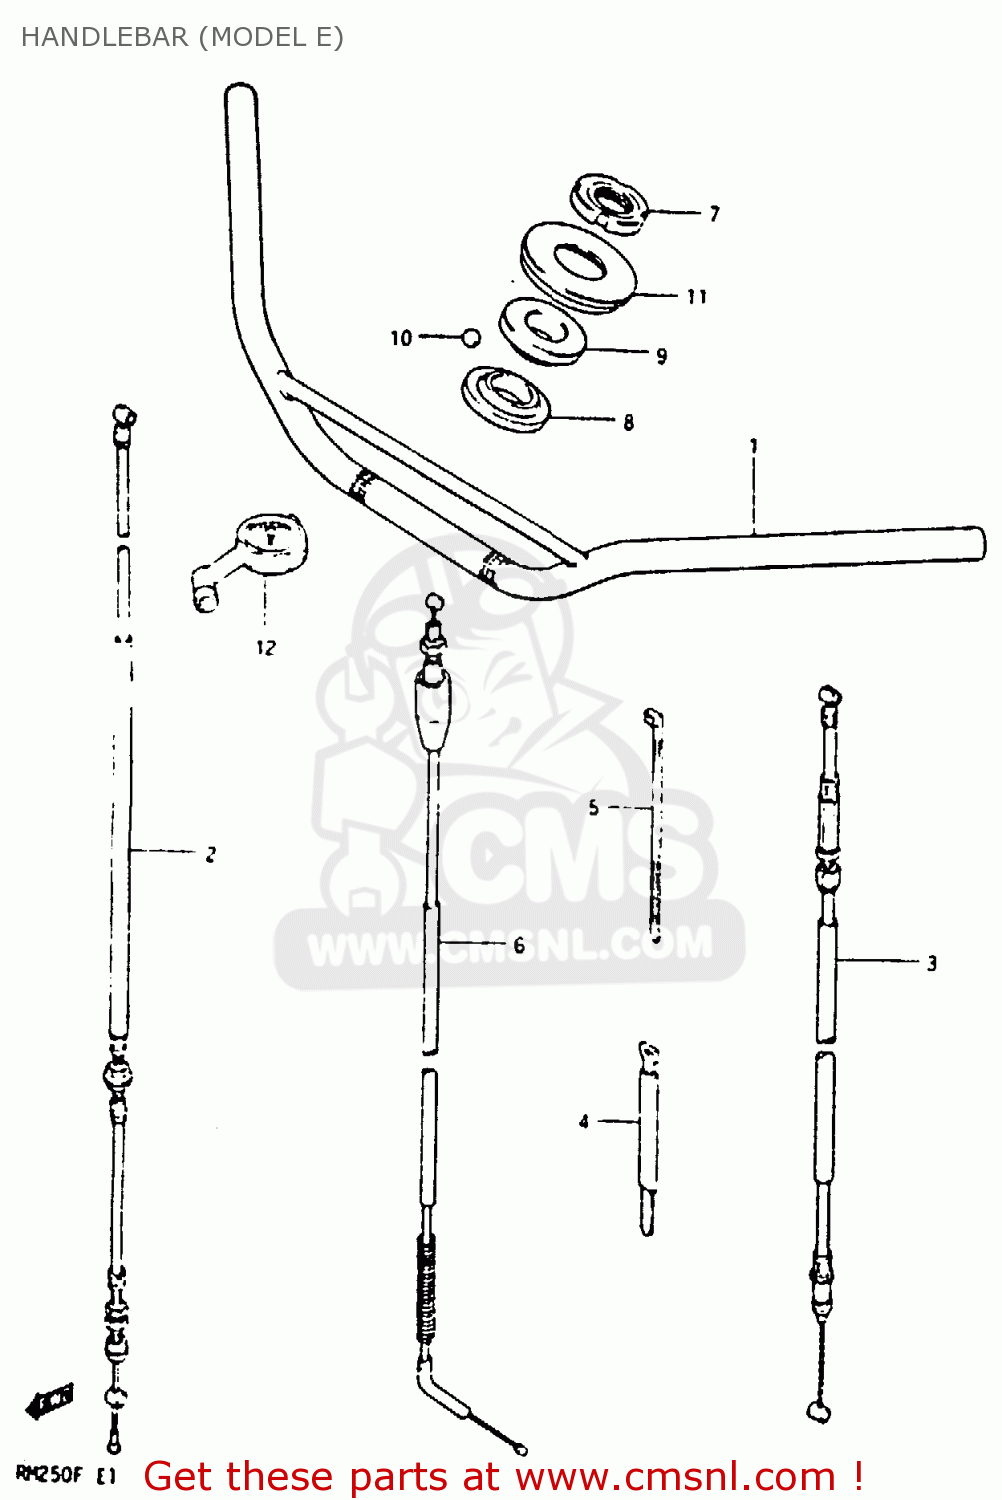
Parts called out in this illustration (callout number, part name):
1	HANDLEBAR
2	CABLE,FRONT BRAKE
3	CABLE ASSY,CLUTCH
4	CLAMP
5	CLAMP(L:235)
6	CABLE ASSEMBLY,THROTTLE
7	NUT,STEERING STEM
8	RACE,STEERING,INNER,UPPER
9	RACE,STEERING,OUTER,UPPER
10	BALL
11	SEAL,STEERING UPR DUST
12	GAUGE ASSEMBLY,AIR PRESSURE
